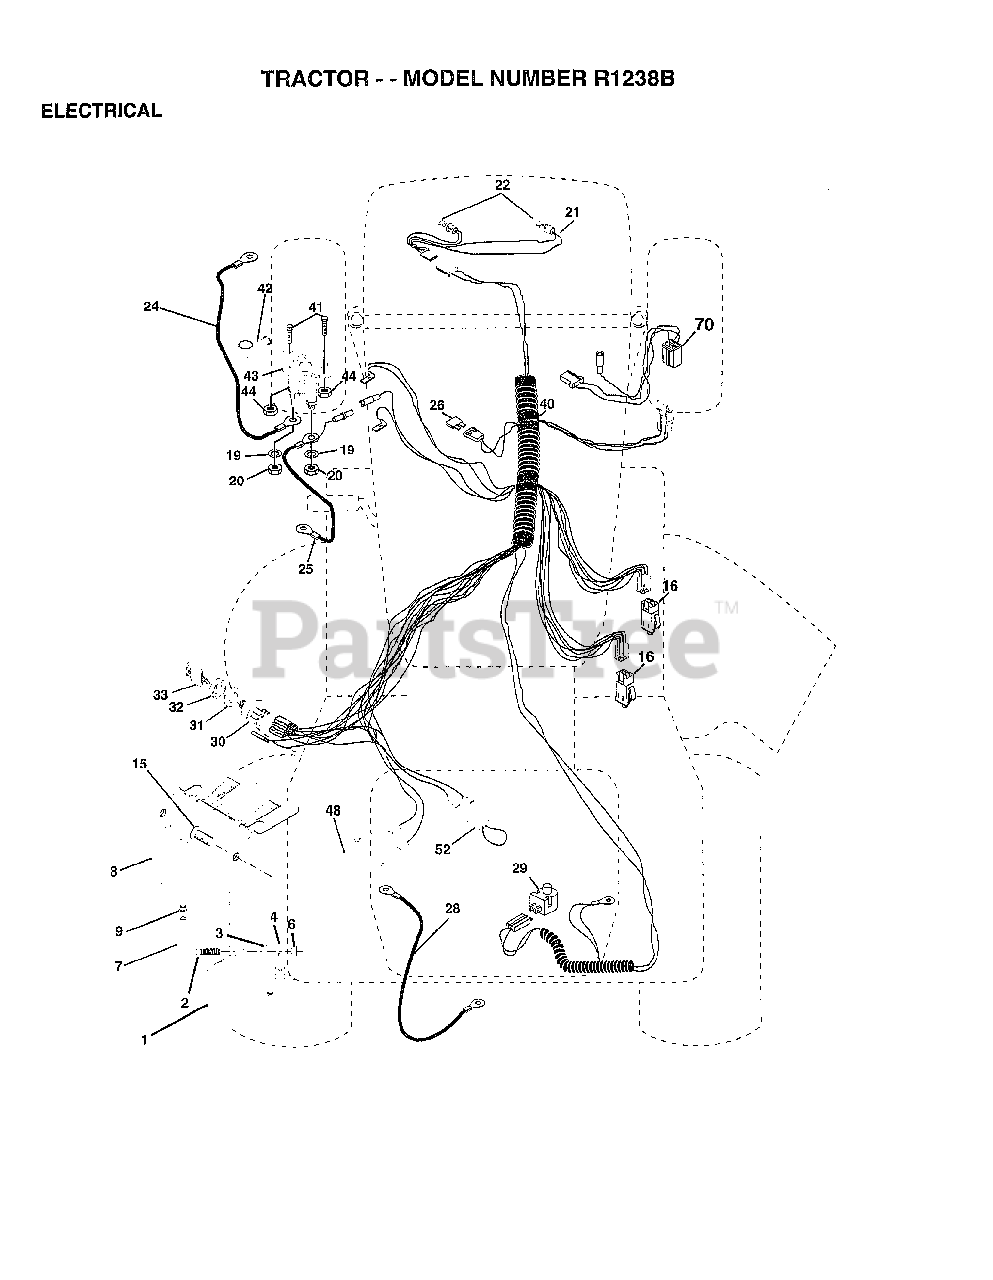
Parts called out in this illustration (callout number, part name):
3	WASHER
4	LOCKWASHER
8	"CASE,BATTERY.MECH"
16	SWITCH INTERLOCK
20	NUT
21	"HARNESS,LIGHT SOC"
22	HEADLAMP BULB
24	"CABLE T, BATTERY"
25	CABLE.BTRY.6GA.RD
26	FUSE HYT
28	CABLE T
29	SWITCH SEAT
30	SWITCH IGN 4POS
31	NUT IGNITION
32	COVER KEY SWITCH
33	KEY
40	HARNESS-IGNITION
41	BOLT HXHD FIN
44	NUT HXKEP 1/4X20
48	ADAPTER AMMETER
52	PROTECTION LOOP
70	HARNESS ENG DUAL
